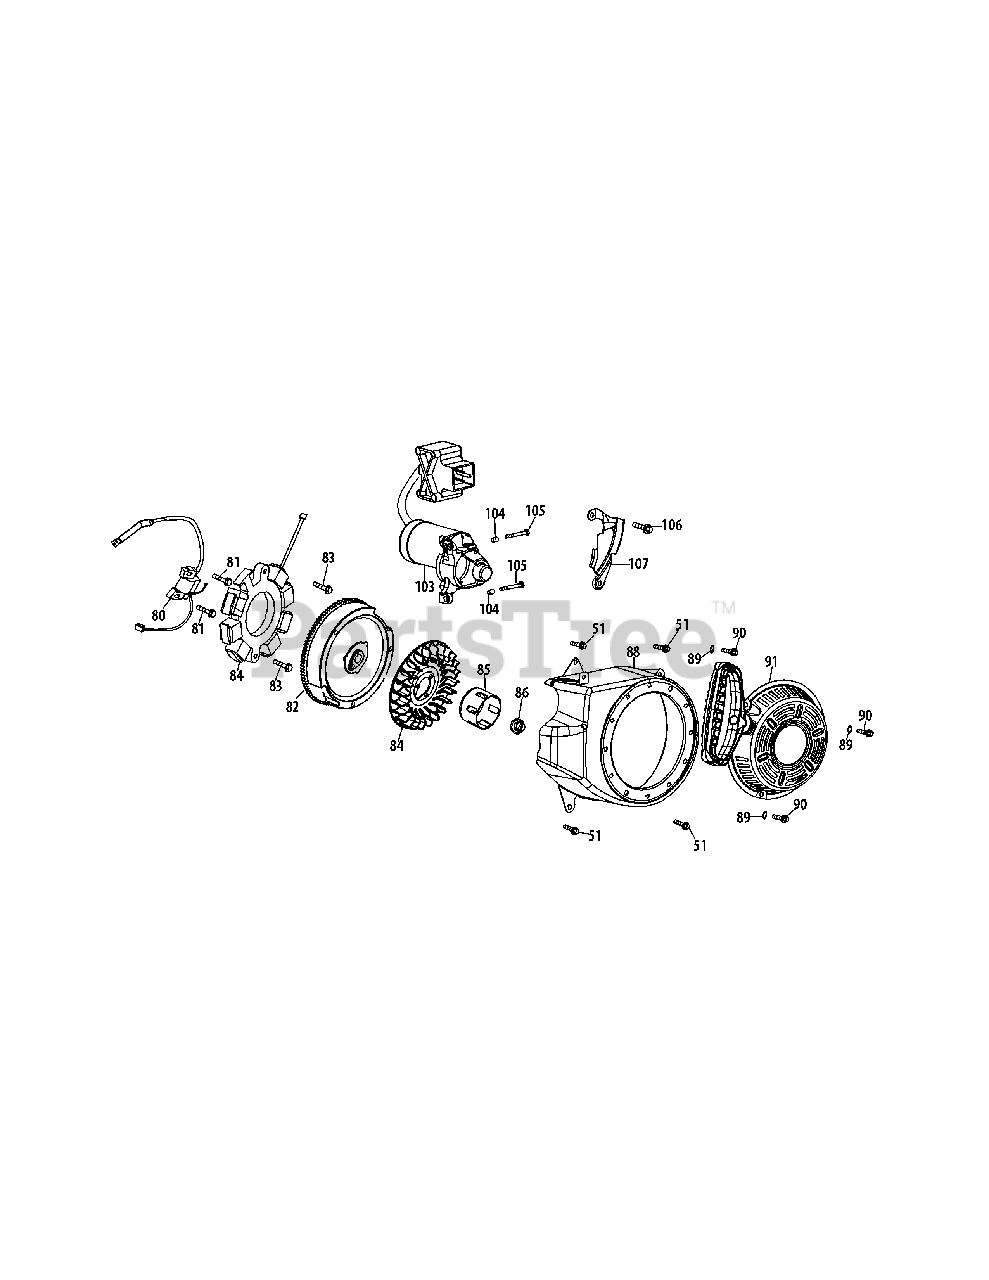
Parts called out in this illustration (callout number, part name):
51	Bolt M6×12
80	Ignition Coil Assembly
81	Bolt M6×25
82	Coil Assy/Stator
84	Fan, Cooling
85	Pulley, Starter
86	Nut, Special, M14×1.5
88	Blower Housing
89	Gasket 6 Washer
90	Bolt M6×10
91	Recoil Starter
91	Recoil Starter Handle
103	Electric Starter
104	Dowel Pin 8×8
105	Bolt M6×32
106	Bolt M6×18
107	Blower Housing Shield
